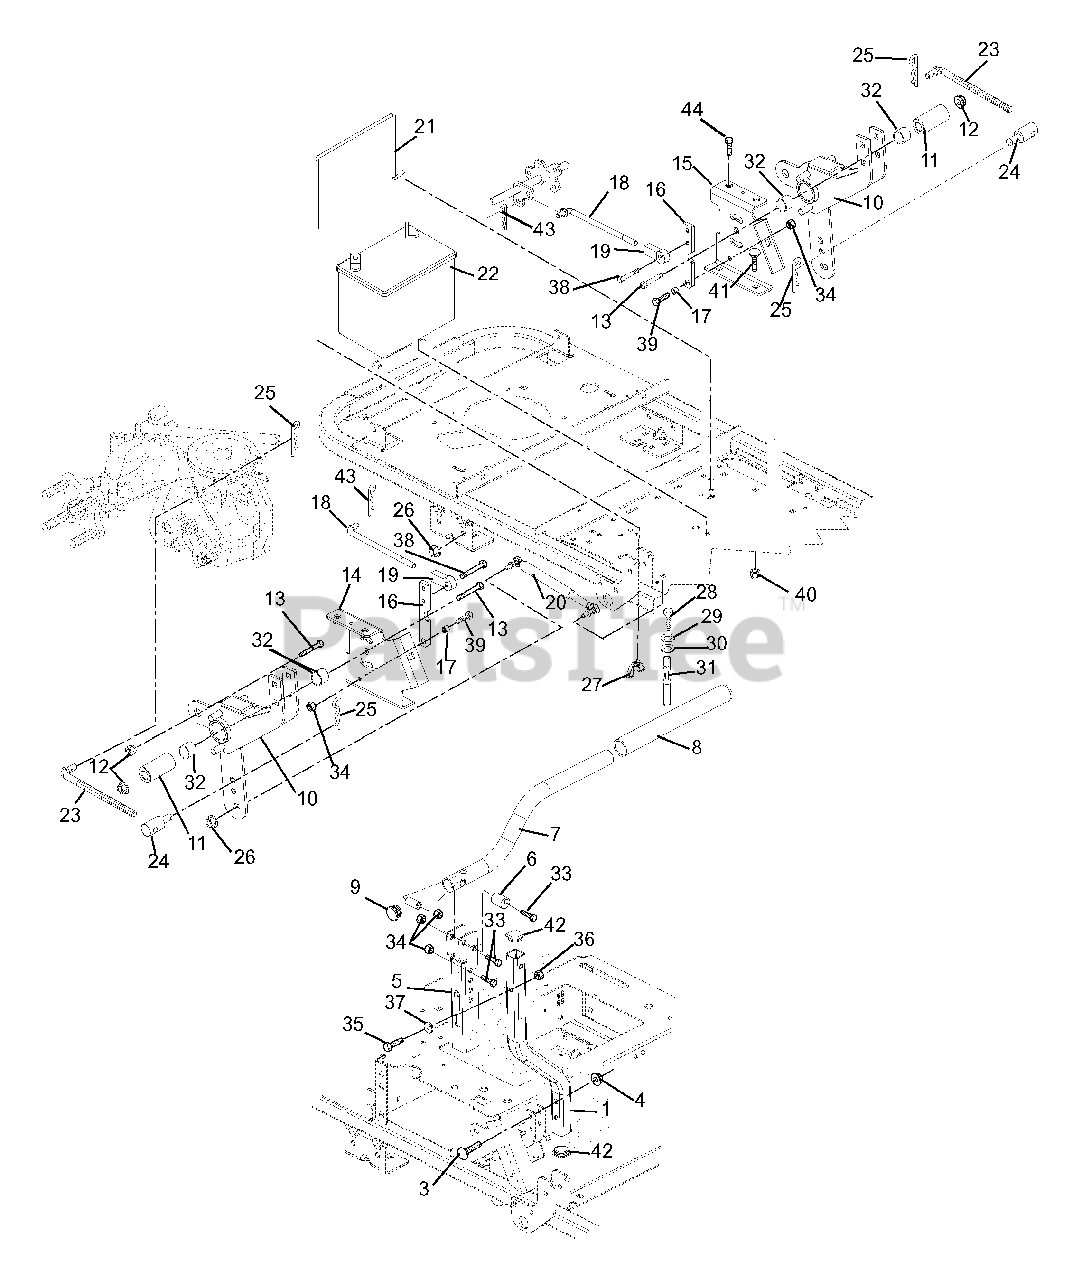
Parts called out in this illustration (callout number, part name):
1	CONTROL ARM
2	CAPLUG SQR 1-14-20
3	@BLT-RDHDSQNK .31-18X1.75 G5YZ
4	@NUT-LK-TOP-FLG .31-18 YWZC
5	CHANNEL, HANDLEBAR ADJUSTMENT
6	BSHG,ECCEN .328X.750X1.01 PM
7	HANDLEBAR
8	GRIP - HANDLEBAR
9	CAPLUG, HANDLEBAR
10	CONTROL WELDMENT
11	BSHG, SPCR .502X.997X2.03 PM
12	@NUT-LK-TOP-FLG .50-13 YWZC
13	@BLT-HEX .50-13X3.00 GR5 YWZC
14	WMT, CONTROL RH
15	WMT, CONTROL LH
16	BRACKET, NEUTRAL STOP
17	BSHG, SPCR .330X.500X.385
18	LINK, BRAKE ROD
19	ROD END, .38 RH
21	BATTERY ROD
22	BATTERY, 300 CCA 10U1L
23	LINK,WIREFORM
24	PIVOT, ROD (TRUNNION ) .50
25	PIN-HAIR, ENDRIES #25 YWZC
26	NUT, TOP LOCK FLG 8X1.25 YWZC
27	NUT-LK WING .250-20 YWZC
28	@BLT-HEX .31-18X1.00 GR5 YWZC
29	@WSHR-LK .31X.078 REG YWZC
30	@WSHR-FL-STL.344X.688X.065YWZC
32	BRG, 1.00 X 1.12 X .75
33	@BLT-HEX .31-18X1.75 GR5 YWZC
34	@NUT-LK-NYL-FLG .31-18 YWZC
35	@BLT-HEX .25-20X1.75 GR5 YWZC
36	@NUT-LK-NYL .250-20 YWZC
37	BSHG-FLG .265X.437X.250X.750
38	@BLT-HEX .38-16X.75 GR5 YWZC
39	@BLT-HEX .31-18X1.25 GR5 YWZC
40	@NUT-LK-NYL-FLG .38-16 YWZC
41	@BLT-RDHDSQNK .38-16X1.00 G5YZ
42	CAPLUG SQR 1-14-20
43	PIN-HAIR INT .08X.18X1.18 YWZC
44	SCR-CAP .38-16X2 HSHD PRECT 30
